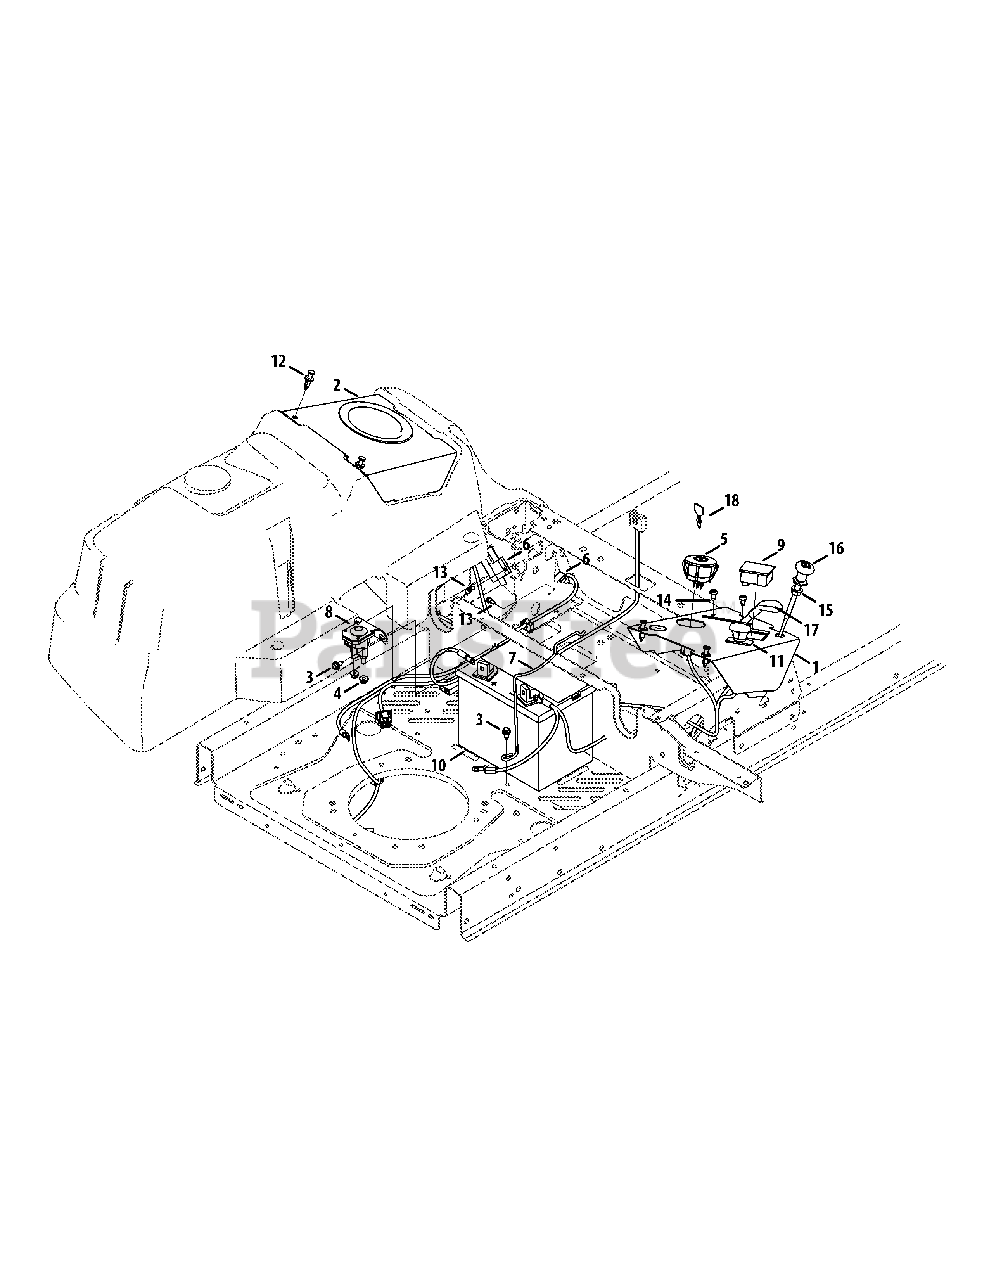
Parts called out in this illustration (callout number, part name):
1	Console Cover, RH
2	Console Cover, LH
3	Hex Washer Screw, 1/4-20 x .625
4	Flange Lock Nut, 1/4-20
5	Key Switch
6	Interlock Switch
8	Solenoid
9	Hour Meter/Service Minder
11	Electric PTO Switch
12	Plastic Rivet
13	Shoulder Screw, #10-32 x .500
14	Screw, 1/4-20 x .50
15	Flange Lock Nut, 3/8-16
16	Choke Cable
17	Throttle Cable
18	Key, Assembly
